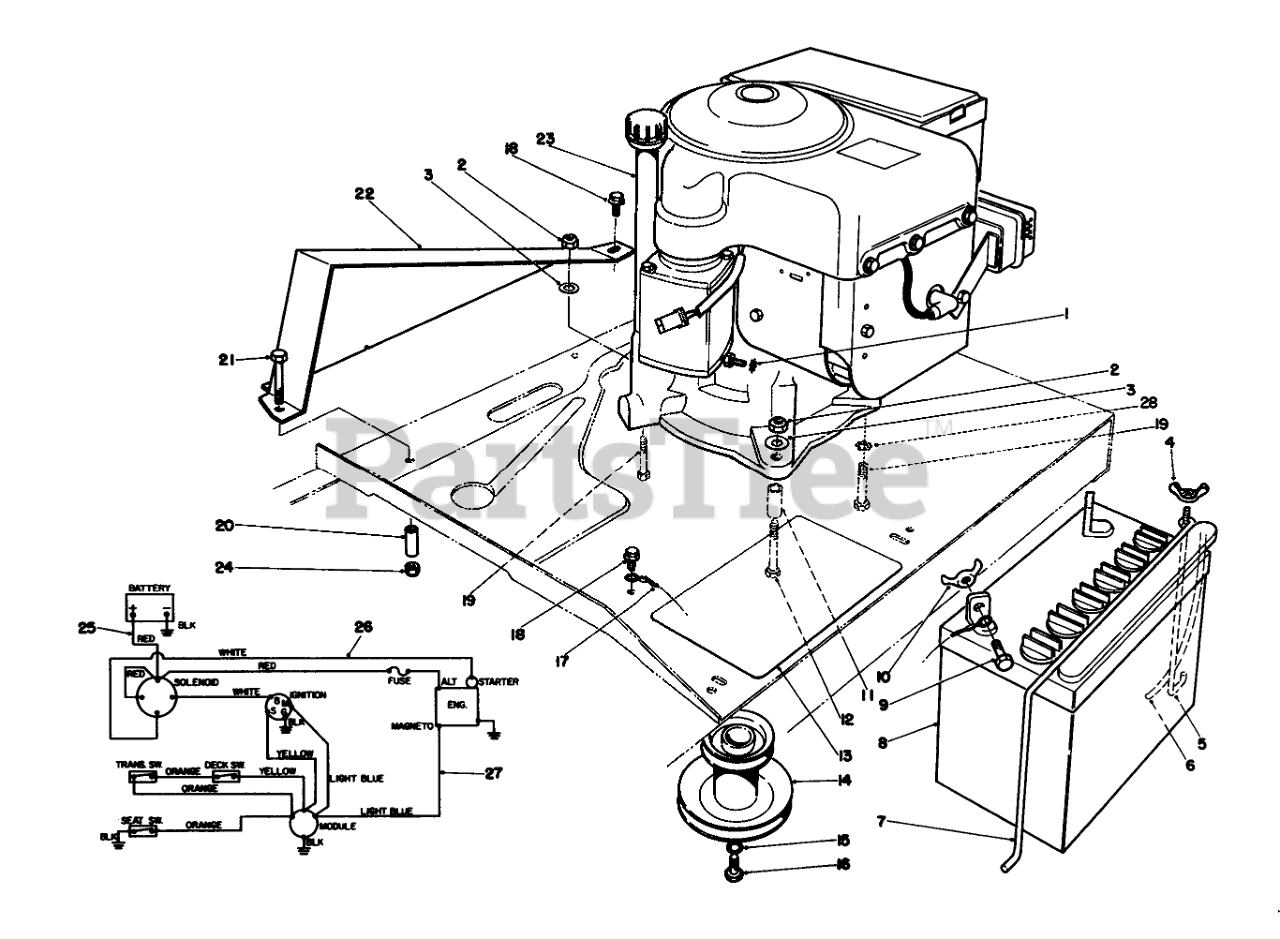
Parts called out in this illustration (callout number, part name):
1	WASHER-LOCK/EXT
2	NUT-LOCK, CONE
3	WASHER-PLAIN
4	NUT-WING SPECL
5	POST-BATTERY
6	TUBE-BATT DRAIN/80-2600
7	BATTERY HOLDOWN
8	Battery
9	SCREW-HH
10	NUT-WING
11	PIVOT SPACER
12	SCREW-HH
13	PAD-SKID, ANTI
14	Pulley-Engine
15	WASHER-LOCK
16	SCREW-HH
17	ENG-GROUND WIRE ASM
18	SCREW-HWHTF
19	SCREW-HH
20	GUIDE-BELT
21	SCREW-HH
22	Guard Chain
24	NUT-LOCK, NI
25	WIRE ASM - BATT TO SOL
26	WIRE ASSEMBLY
27	WIRE HARNESS
28	WASHER-LOCK
